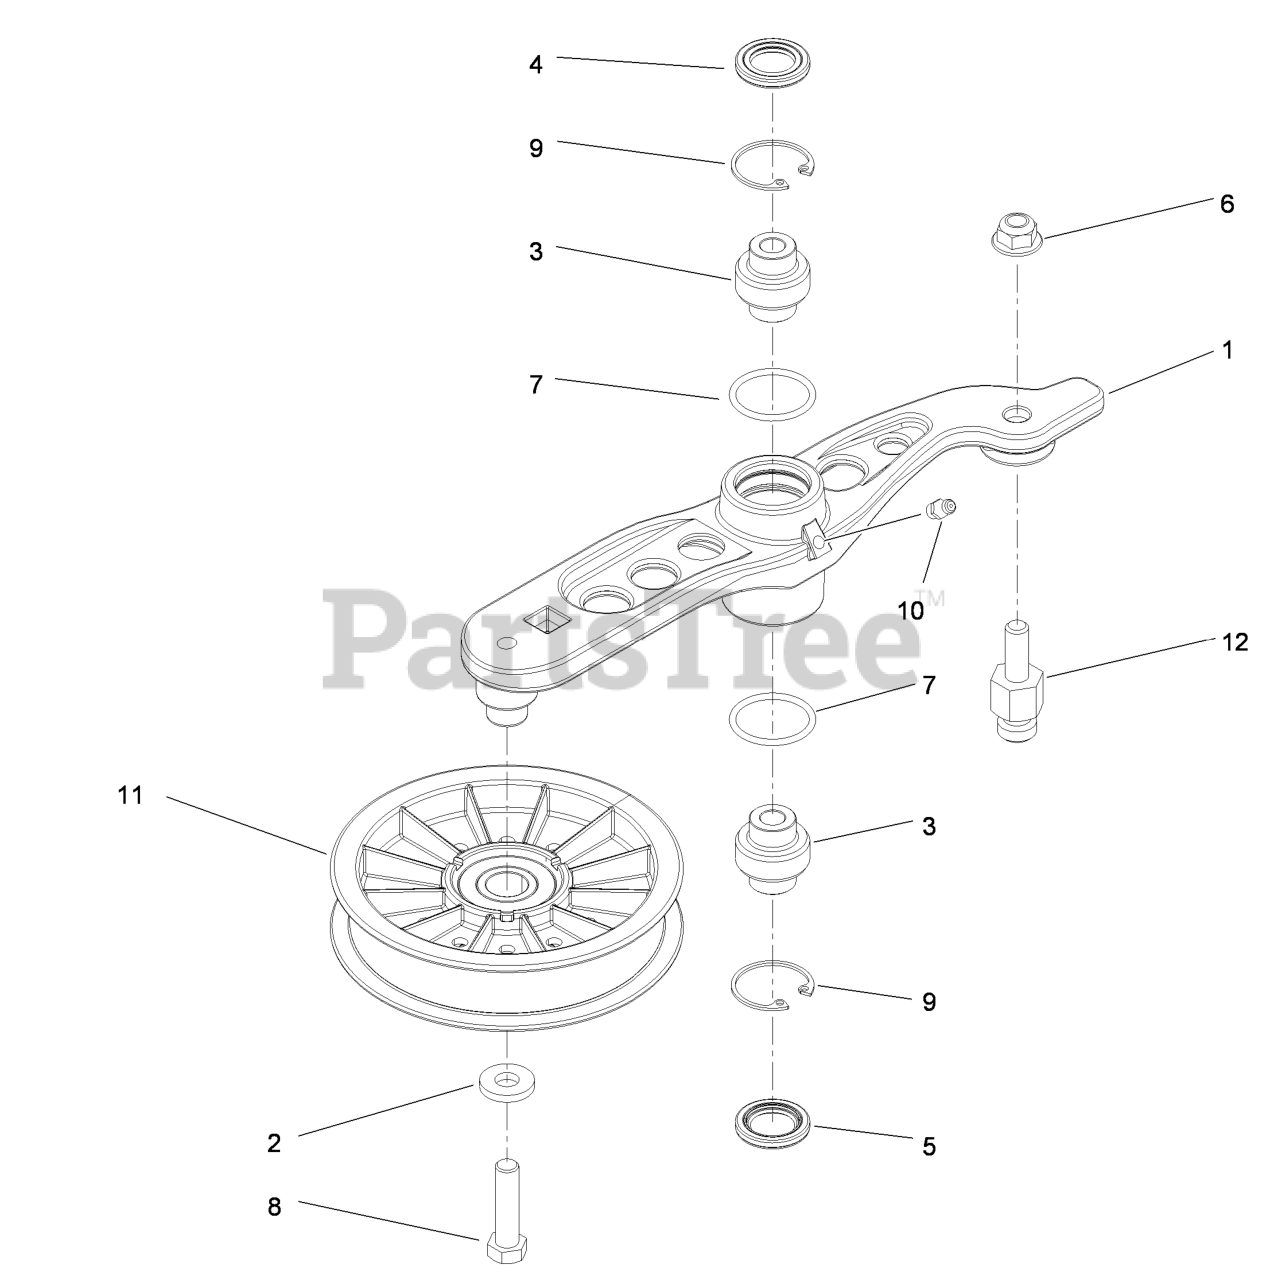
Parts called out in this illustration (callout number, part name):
1	Arm-Pump, Idler
3	BEARING-SPHERICAL
4	SEAL-LIP, DOUBLE
5	SEAL-LIP, SINGLE
6	Nut-Nyloc 3/8-16 Flg
8	SCREW-HH
9	RING-SNAP
10	FITTING-GREASE
11	PULLEY-IDLER
